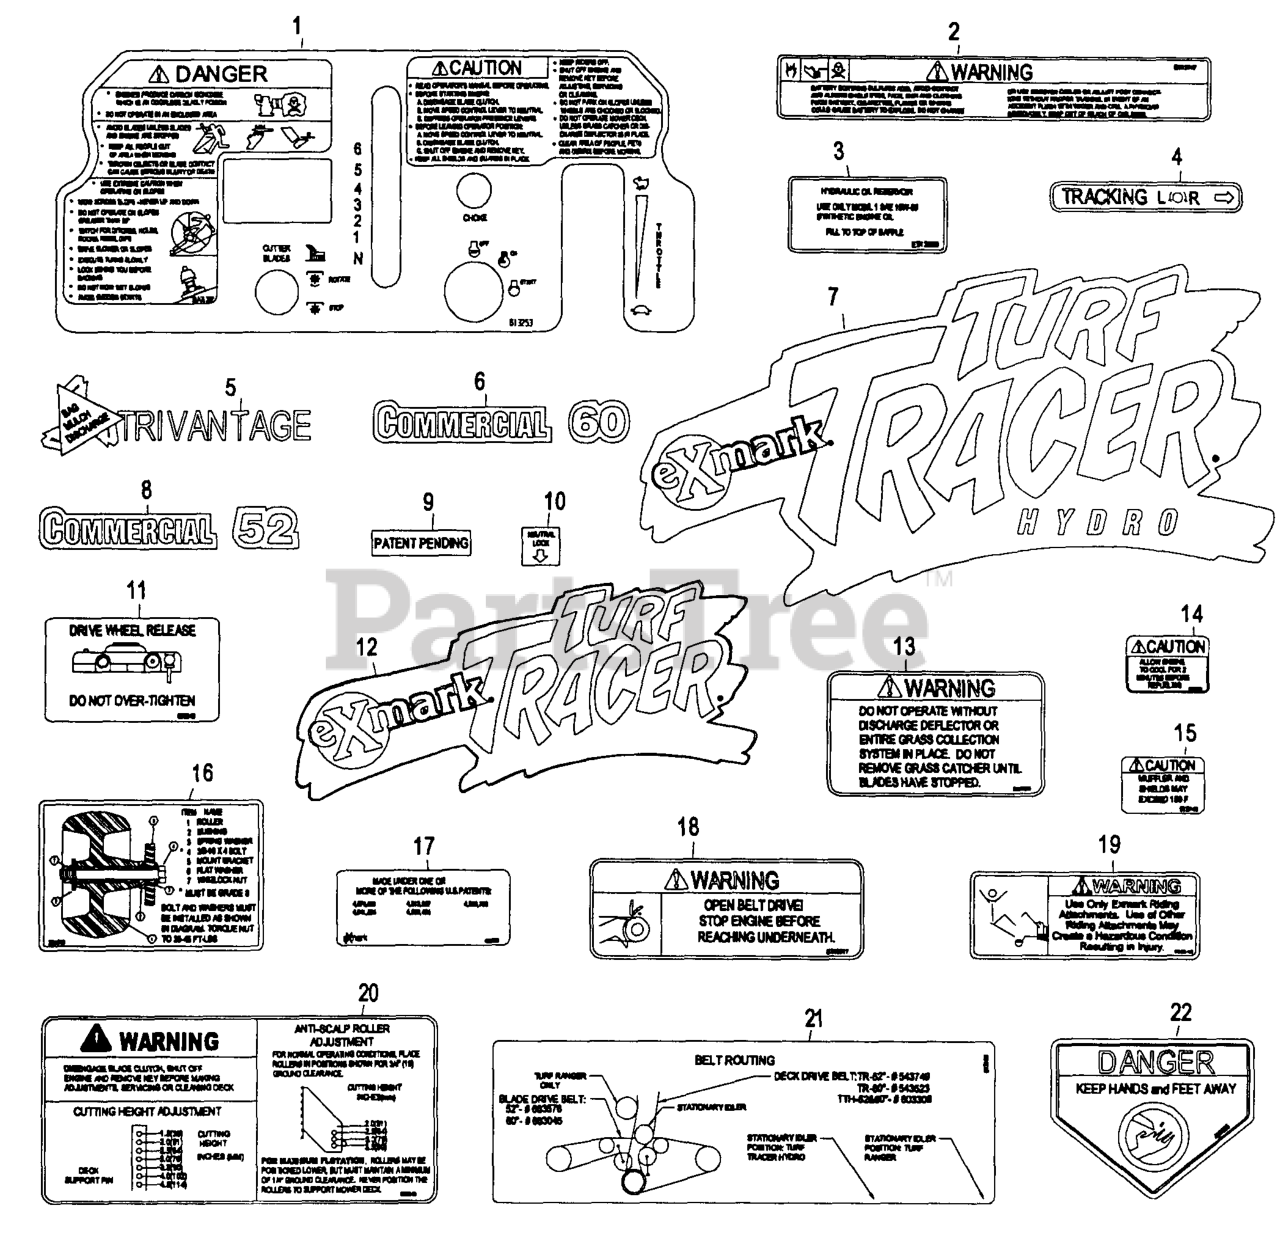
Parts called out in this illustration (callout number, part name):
2	DECAL-BATTERY
3	DECAL,HYD TANK
4	DECAL,TRACKING ADJUST
6	DECAL,COMMERCIAL 60
8	DECAL,COMMERCIAL 52
9	Decal, Patent Pending
10	DECAL,NEUTRAL LOCK
11	DECAL,DRIVE RELEASE
13	DECAL-WARNING, DISCHARGE
16	DECAL,ROLLER MOUNTING
18	DECAL,BELT DRIVE
19	DECAL,SULKY WARNING
20	DECAL,ANTI SCALP
21	DECAL,BELT ROUTING
22	DECAL-DANGER
